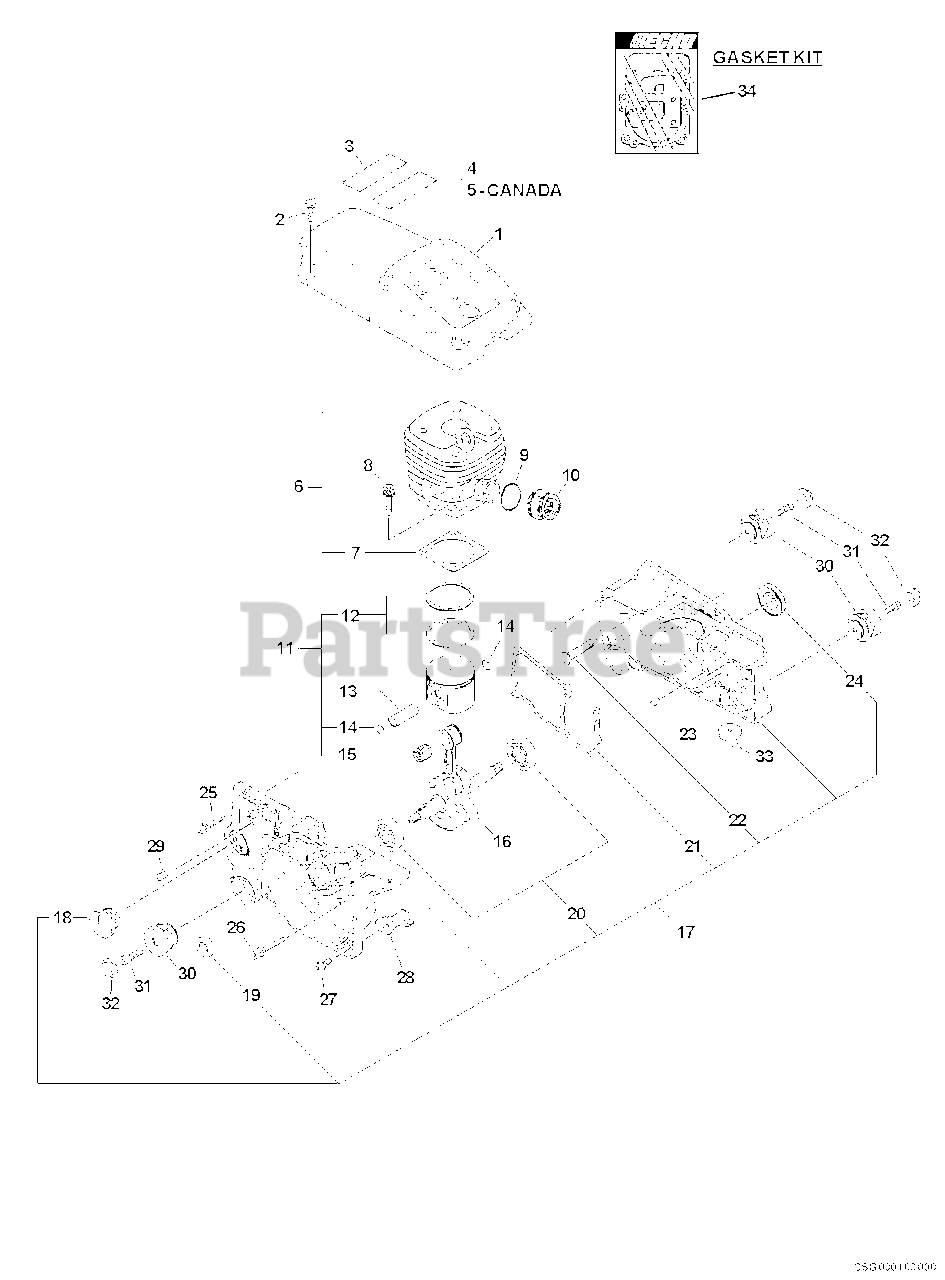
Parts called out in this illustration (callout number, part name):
1	COVER, ENGINE
2	SCREW - 5X20
3	LABEL - CAUTION
4	LABEL - CAUTION
5	LABEL - CAUTION
6	CYLINDER KIT
7	GASKET, CYLINDER
8	SCREW - 5X20
10	BELLOWS, INTAKE
11	PISTON KIT
12	RING, PISTON
13	PIN, PISTON
14	RING, RETAINING
15	BEARING, NEEDLE
16	CRANKSHAFT ASSY
17	CRANKCASE KIT
18	CAP, OIL TANK
19	SEAL, OIL
20	BEARING, BALL - 6202
21	GASKET, CRANKCASE
22	STUD, GUIDE BAR
23	PIN - LOCATING
24	SEAL, OIL
25	SCREW - 5X20
26	SCREW - 5X35
27	SCREW - 5X14
29	VENT, TANK
31	SCREW - 5X14
32	CAP, CUSHION
33	CUSHION - A
34	GASKET KIT
